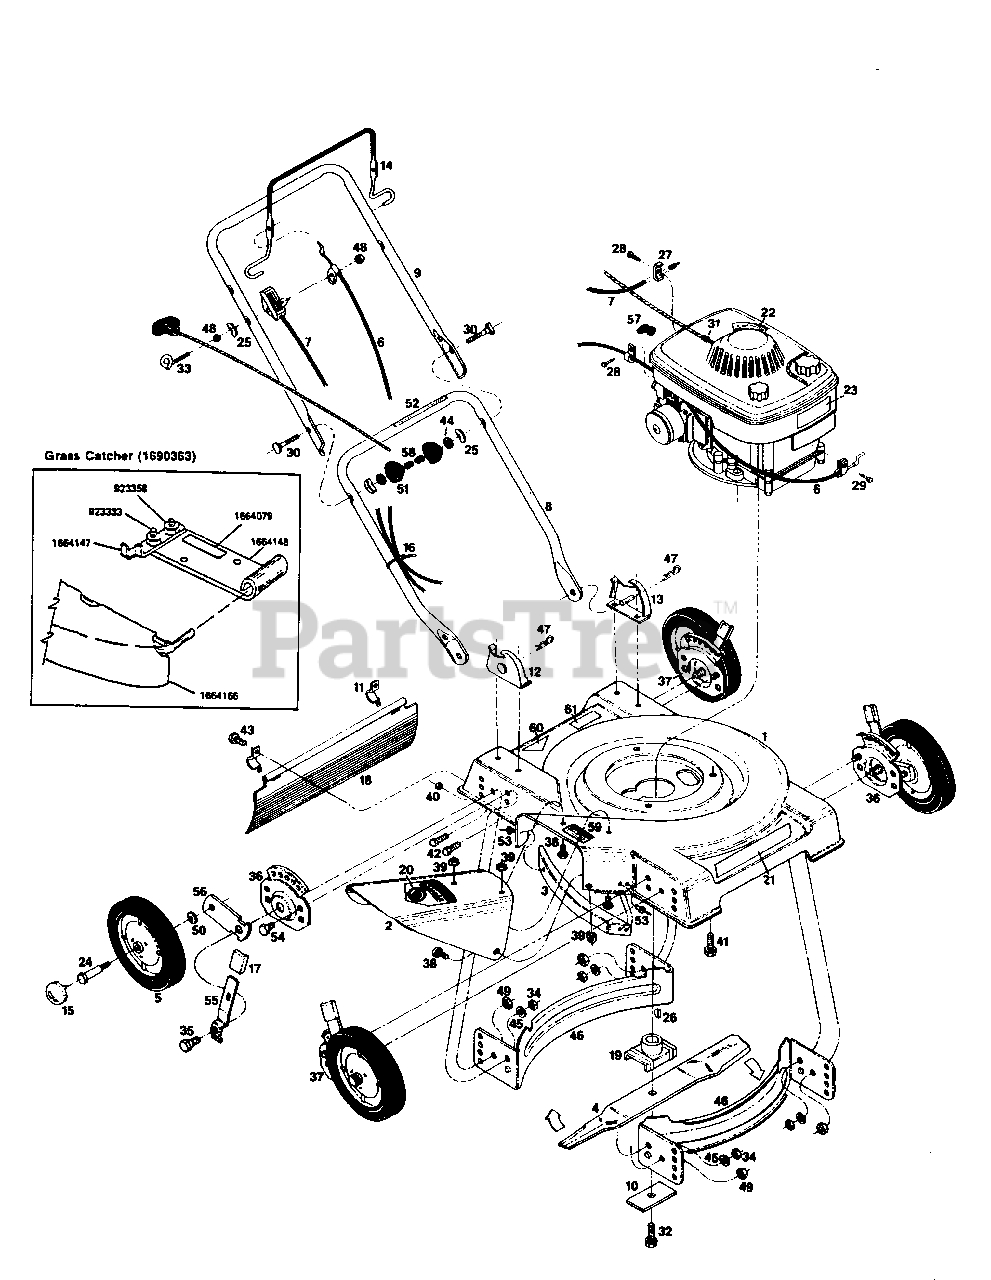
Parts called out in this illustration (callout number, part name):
2	Extension-Discharge Chute
3	Guard-Blade
5	Wheel 7 x 1.50
6	Cable-Engine/Blade Control
7	Control-Throttle, with cable
8	Handle-Lower
9	Handle-Upper
10	Washer-Blade
11	Clip-Trailing Shield
12	Bracket-Handle RH
13	Bracket-Handle LH
14	Bail-Engine/Blade Control
17	Tip-Adjuster Lever
18	Shield-Trailing
19	Adapter-Blade
20	Decal-Danger, Discharge Chute
21	Decal-Simplicity
22	Decal-Blade Warning
23	Decal-3.5HP
24	Bolt-Wheel
25	Washer-Curved 5/16
26	Key-Woodruff #6
27	Clamp-Throttle Cable
28	Screw-Self Tap #10 x 5/8
29	Screw-Hex #10-32 x 3/8
30	Bolt-Curved Head 5/16-18 x 2 1/4
31	Stop-Rope
32	Bolt-Blade w/Lockwasher
33	Eyebolt-Rope Guide
34	Nut-Hex, 1/4-20 Lock
35	Bolt-Shoulder 3/8-16
36	Plate-Height Adjuster RH Rear, LH Front
37	Plate-Height Adjuster LH Rear, RH Front
38	Bolt-Carriage #10-24 x 1/2
39	Nut-Hex #10-24 Keps
40	Nut-Hex #10-24 Nylok
41	Bolt-Self Tap 3/8-16 x 7/8
42	Bolt-Self Tap 1/4-20 x 1/2
43	Bolt-Hex #10-24 x 1/2
44	Washer-Shakeproof 5/16
45	Washer-Fiat 1/4
46	Baffle-Deck
47	Cotter-Hairpin
48	Nut-Hex 1/4-20 Keps
49	Nut-Hex 3/8-16 Lock
50	Washer-Belleville
51	Knob-Handle Retaining
52	Decal-Starting Instructions
53	Rivet-Pop 1/4 Steel
54	Bolt-Hex 1/4-20 x 3/4
55	Lever-Height Adjustment
56	Arm-Wheel
57	Boot-Spark Plug
58	Cap-Plastic, Bolt End
59	Decal-Warning, Chute Deflector in Place
60	DECAL, OPEI
61	DECAL, Model Number
